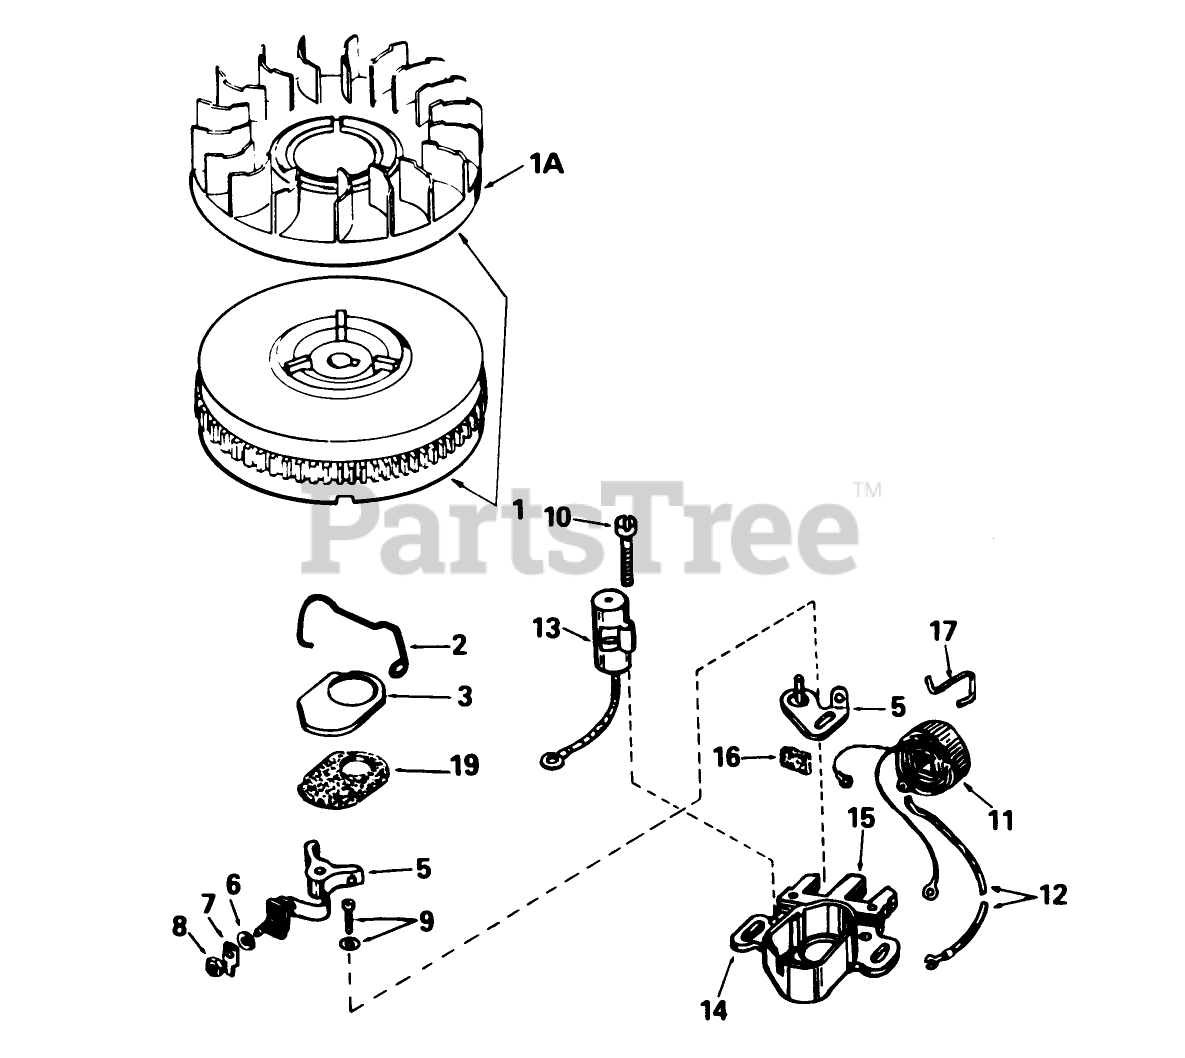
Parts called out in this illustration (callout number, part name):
1	Flywheel (Incl. Ref. #1A)
1A	Fan
2	Spring Breaker Box
3	Cover-Dust
5	Breaker Assy.
6	Washer
7	Terminal, Ground
8	DECAL
9	Breaker Screw
10	Condenser Screw
11	Coil Assy. (Incl. No. 12)
12	Wire, Lead
13	Condenser
14	Core Plate
15	Stator Assy. (Incl. Ref. #2 thru 11, 13, 14, 16, 17 19)
16	Felt,Cam Wiper
17	Clip, Coil
19	Gasket, Dust Cover
